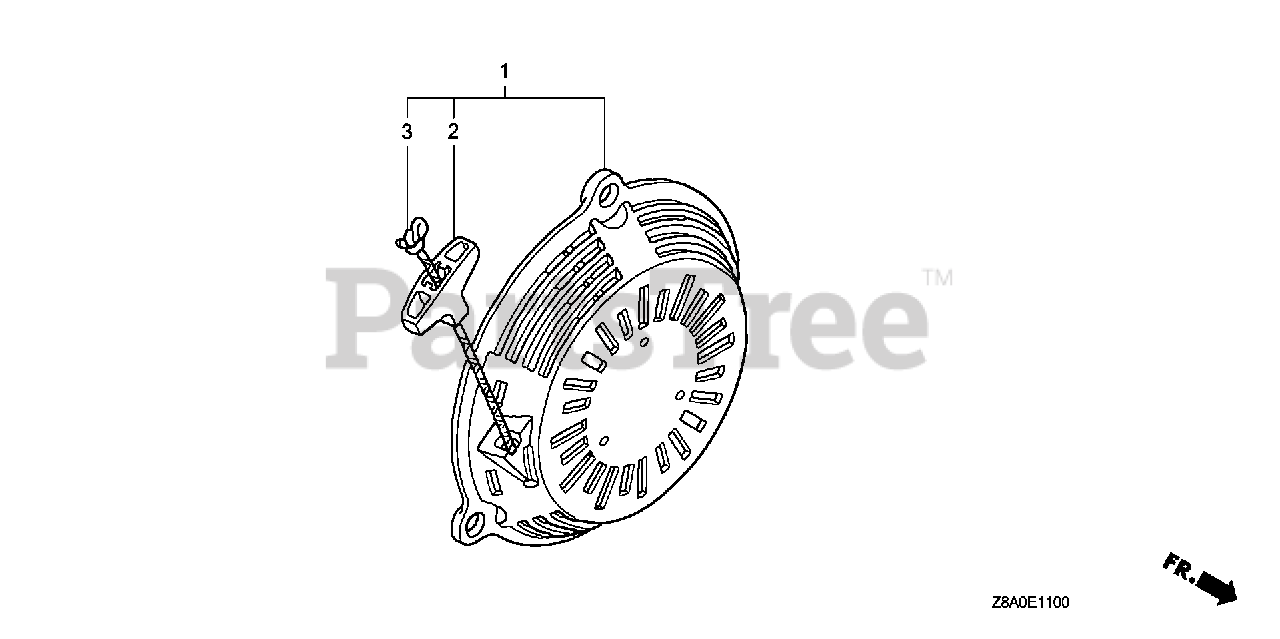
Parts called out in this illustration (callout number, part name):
1	STARTER ASSY., RECOIL *NH1* (LONG ROPE) (BLACK)
2	GRIP, STARTER
3	ROPE, RECOIL STARTER (LONG TYPE) (NOT AVAILABLE)
